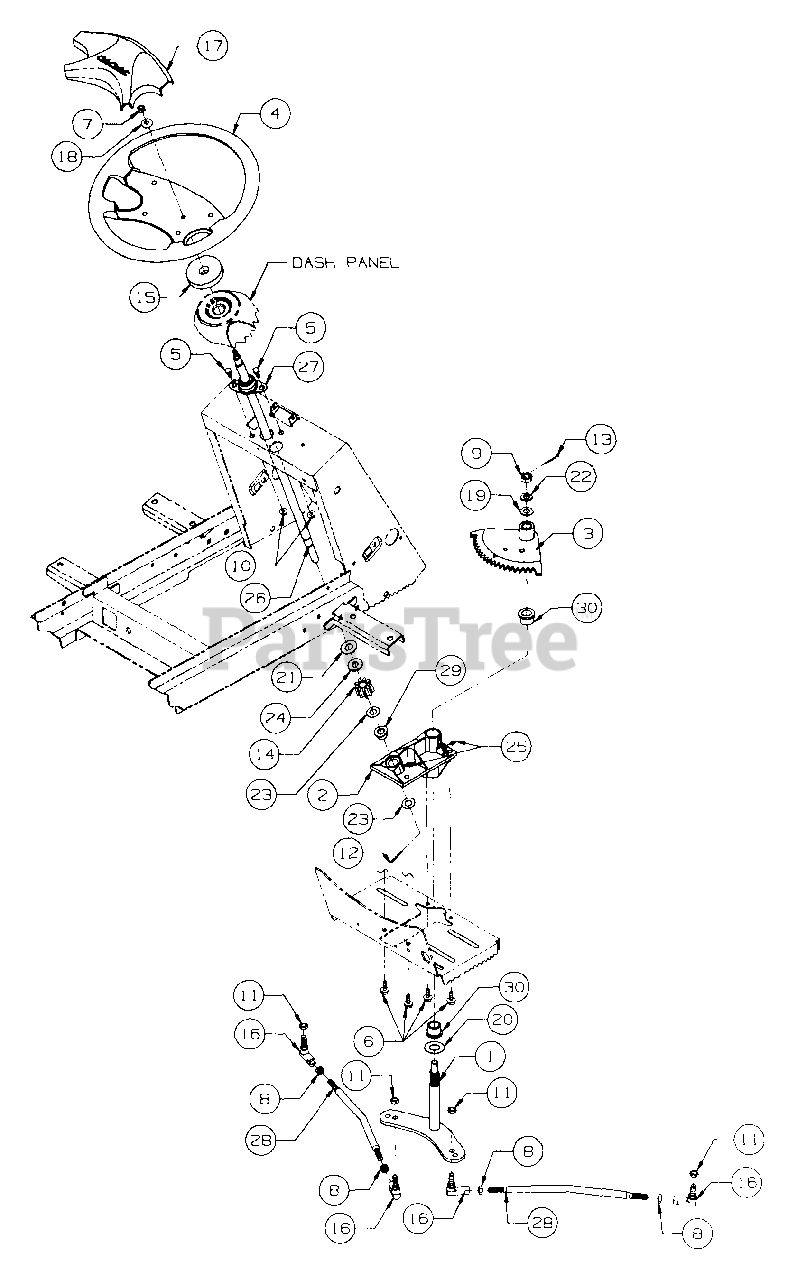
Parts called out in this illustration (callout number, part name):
1	Arm Assy, Lower Steering
2	Housing Assy, Steering
3	Segment Assy, 18T - Steering
4	Wheel, Steering
5	Screw, Hex Cap, 1/4-20 x .62 Lg
6	Screw, Hex Wash HD-TPTT, 5/16-18 x .75 Lg
7	Nut, Hex Center Lock, 5/16-24
8	Nut, Hex Jam, 3/8-24 GR5
9	Nut, Hex Slotted, 1/2-20 GR5
10	Nut, Hex Flange Lock, 1/4-20
11	Nut, Hex Lock, 3/8-24 GR5
12	Pin, Cotter, 1/8 Dia x 1.0 Lg
13	Pin, Cotter, 3/32 Dia x 1.25 Lg
14	Pinion, Steering
15	Gasket, Steering
16	Joint, Bail, 3/8-24
17	Insert, Steering Wheel, Cub Cadet
18	Washer, Bell, .340 x .88 x .06 Thk
19	Washer, Flat, .510 x 1.0 x .06 Thk
20	Washer, Flat, .760 x 1.50 x .030 Thk
21	Washer, Flat, .56 x 1.0 x .040 Thk
22	Washer, Lock, 1/2
23	Washer, Flat, .531 x 1.0 x .027 Thk
24	Washer, Rubber, Flat, .50 x 1.12 x .125 Thk
25	Fitting, Lube, 3/16 Drive Type
26	Shaft, Steering
27	Bearing, Flange
29	Bearing, Flange, .503 ID
30	Bearing, Bronze Flange, .75 ID
